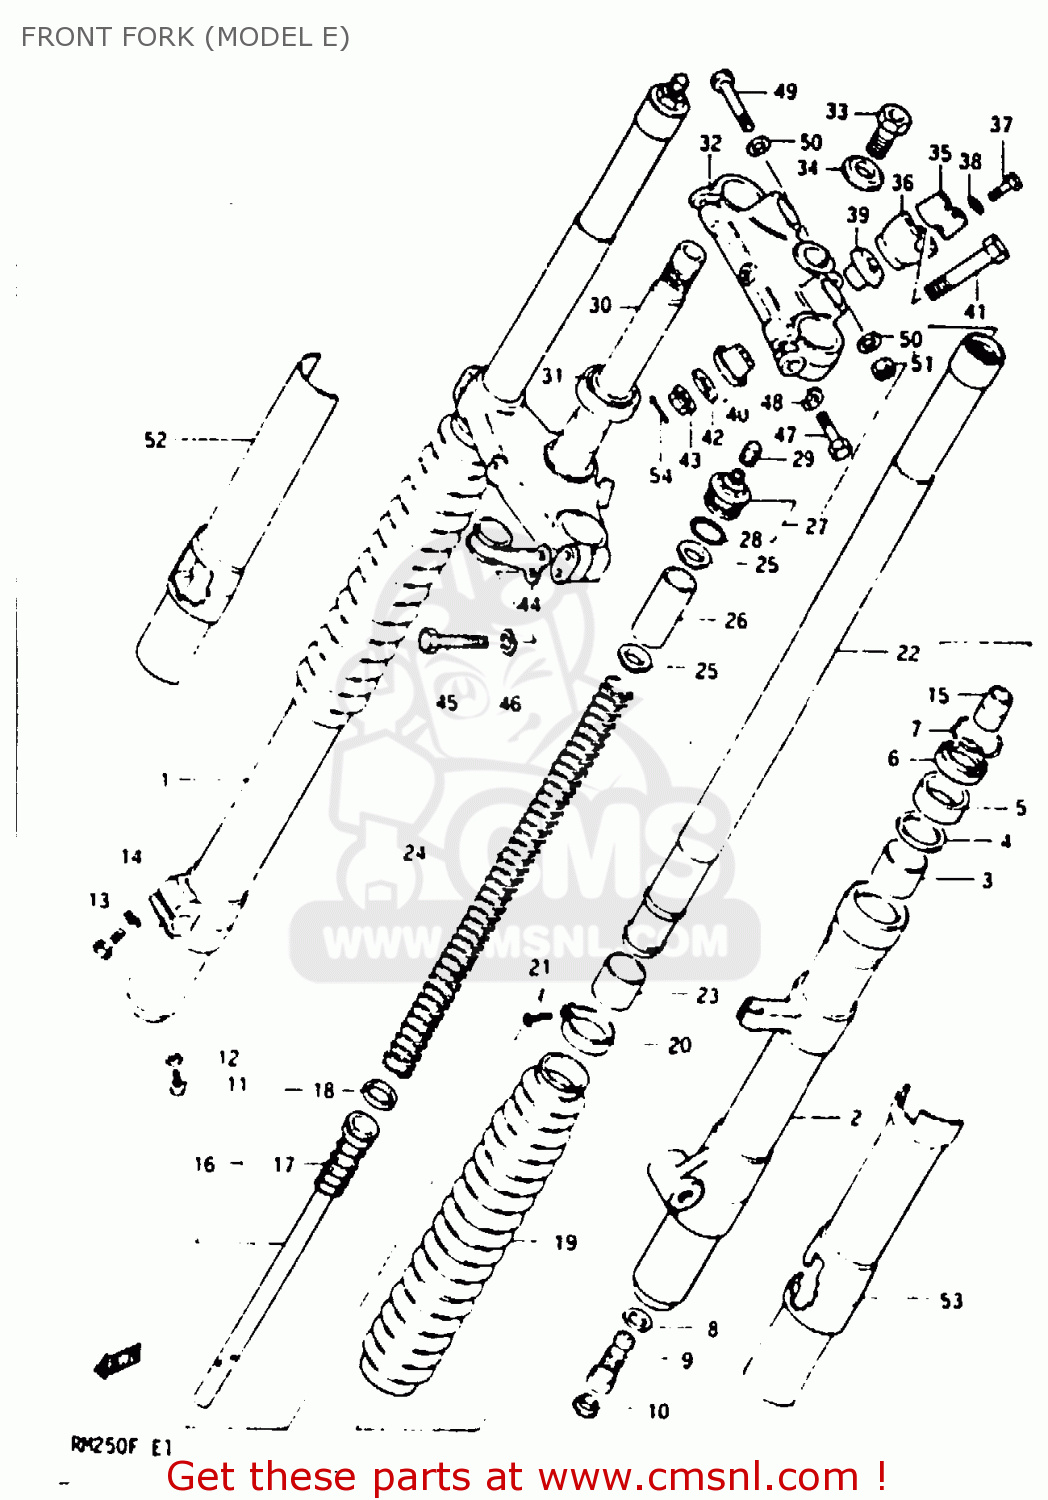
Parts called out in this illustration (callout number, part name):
1	TUBE,OUTER,RIGHT
2	TUBE,OUTER,LEFT
3	METAL,SLIDE
4	WASHER
5	SEAL,OIL
6	SEAL,DUST
7	RING,STOPPER
8	GASKET,FORK CYLINDER
9	VALVE,DF
10	CAP,FRONT FORK DF
11	SCREW 4X6
12	GASKET,DRAIN,PLUG (NAS)
13	BOLT (8X30)
14	WASHER,LOCK,8.
15	PIECE,FRONT FORK OIL LOCK
16	CYLINDER,FRONT FORK
17	SPRING,REBOUND
18	RING,FRONT FORK PISTON
19	BOOT,FRONT FORK COVER
20	BAND,BOOT,UPPER
21	SCREW 4X10
22	TUBE,FORK,INNER
23	PISTON
24	SPRING,FRONT FORK
25	GUIDE,FRONT FORK SPRING
26	SPACER,FRONT FORK SPRING
27	CAP,FORK INNER TUBE
28	O RING
29	CAP
30	STEM,STEERING
31	BEARING
32	HEAD,STEERING STEM
33	BOLT
34	WASHER
35	HOLDER,HANDLEBAR
36	HOLDER,HANDLE LWR
37	BOLT
38	WASHER,LOCK,8.
39	DAMPER,UPR
40	DAMPER,LWR
41	BOLT,HANDLE HOLDER
42	WASHER,HANDLEBAR HOLDER
43	NUT
44	GUIDE,CABLE
45	BOLT 8X40
46	WASHER,LOCK,8.
47	BOLT
48	LOCK WASHER
49	BOLT 8X50
50	WASHER
51	NUT
52	PROTECTOR,RIGHT
53	PROTECTOR
54	PIN 20X20
